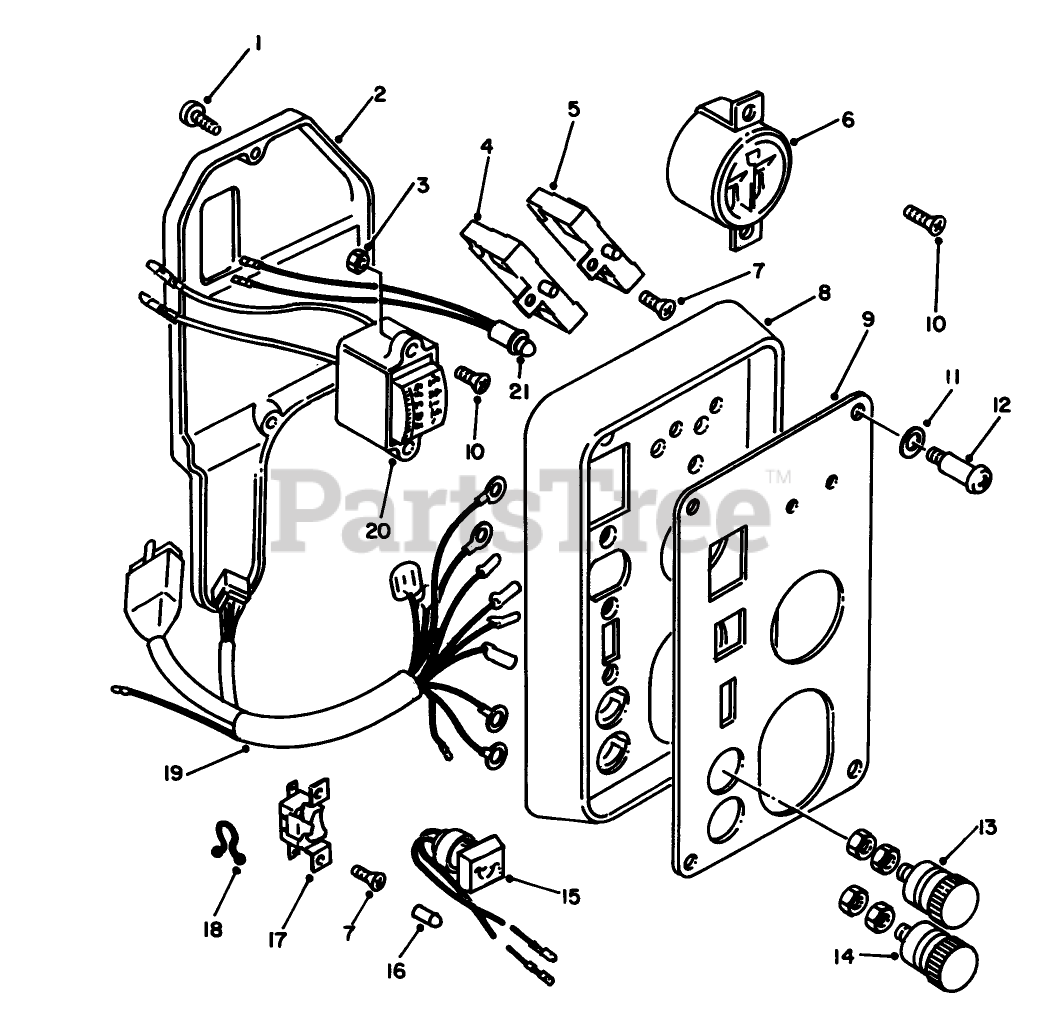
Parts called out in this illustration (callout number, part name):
1	Screw
2	Cover-Panel
4	Circuit Breaker(4.0A)
5	Circuit Breaker (15A)
6	Receptacle
7	Screw
8	Panel-Control
9	Plate-Panel
10	Screw
11	Washer
12	SCREW
13	Terminal (+)
14	Terminal (-)
15	Lamp-Oil Level
17	Switch
18	Clamp
19	Harness-Control
20	Hertz Meter
21	CYCLE METER LAMP ASM
